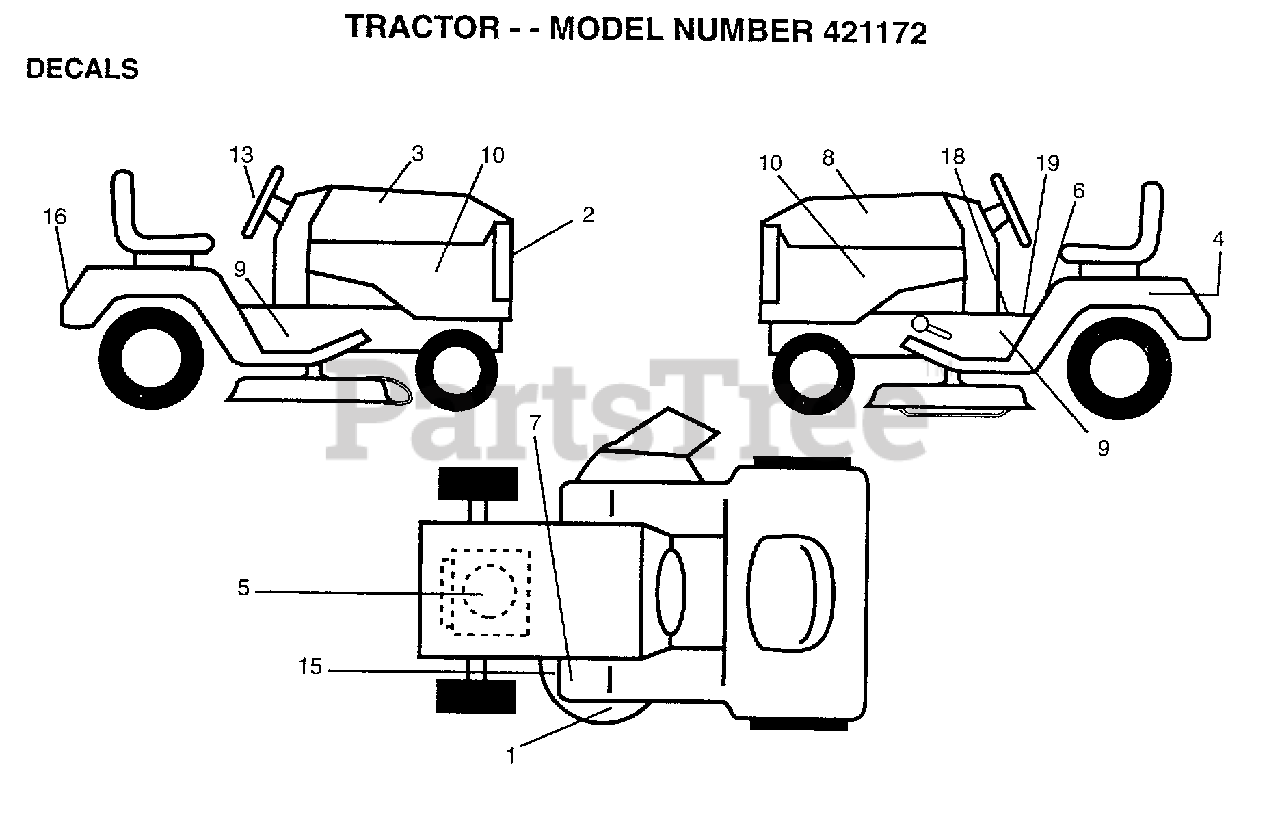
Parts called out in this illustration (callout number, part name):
2	DECAL.LENS.YP.EUR
3	DECAL.HD.RH.
4	DECAL.BTRY.DANGER
5	DECAL ENGINE
6	DECAL
8	DECAL.HD.LH.
9	DECAL CHAS 42 HYD
10	DECAL.PANEL.SD.
13	DECAL.INS.STRG.WH
15	DECAL
18	DECAL SADLE HYDRO
